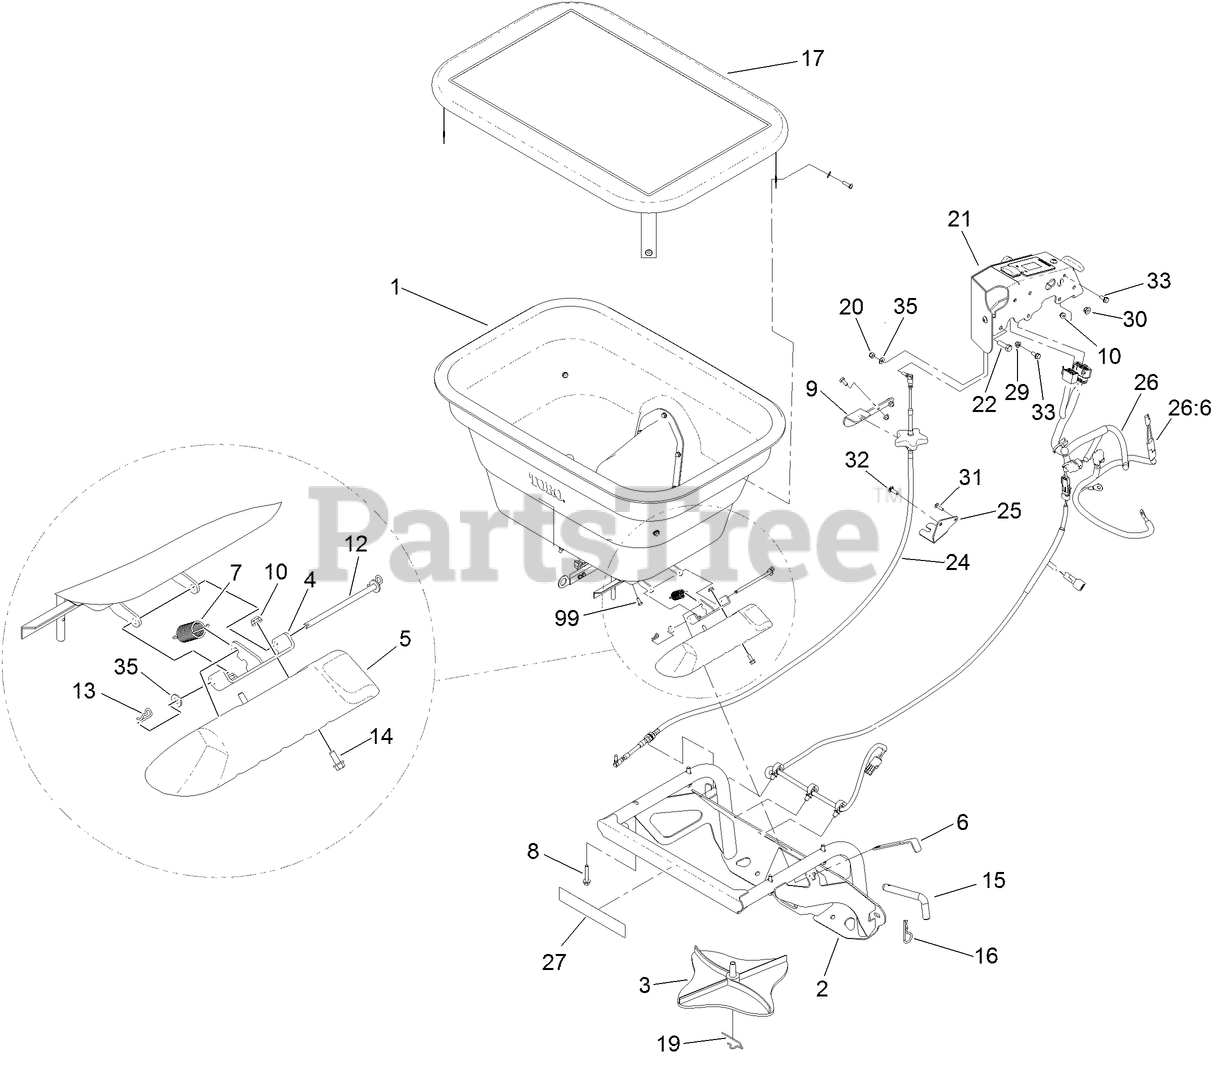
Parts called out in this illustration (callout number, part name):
1	SPREADER HOPPER ASM
2	SPREADER HOPPER FRAME ASM
3	SPINNER-SPREADER
4	BRACKET-DEFLECTOR
5	DEFLECTOR
6	STRAP-ENGAGEMENT
7	SPRING-EXTENSION
8	SCREW-HWH
9	BRACKET-CABLE
10	NUT-HF
12	PIN-PIVOT
13	PIN-COTTER
14	SCREW-HEAD, FLANGE
15	PIN-HITCH
16	PIN-HAIR
17	COVER-HOPPER
19	CLIP-SPINNER
20	NUT-LOCK
21	SPREADER CONTROLLER ASM
22	SCREW-HH
24	CABLE-PUSH, PULL
25	BRACKET-CABLE
26	HARNESS
26:6	CONNECTOR
27	DECAL-DOWN, TIE
29	NUT-HF, NI
30	NUT-HF, NI
31	SCREW-CARR
32	SCREW-CARR
33	SCREW-HHF
35	WASHER-FLAT
99	NUT-HF
99	SCREW-HH
